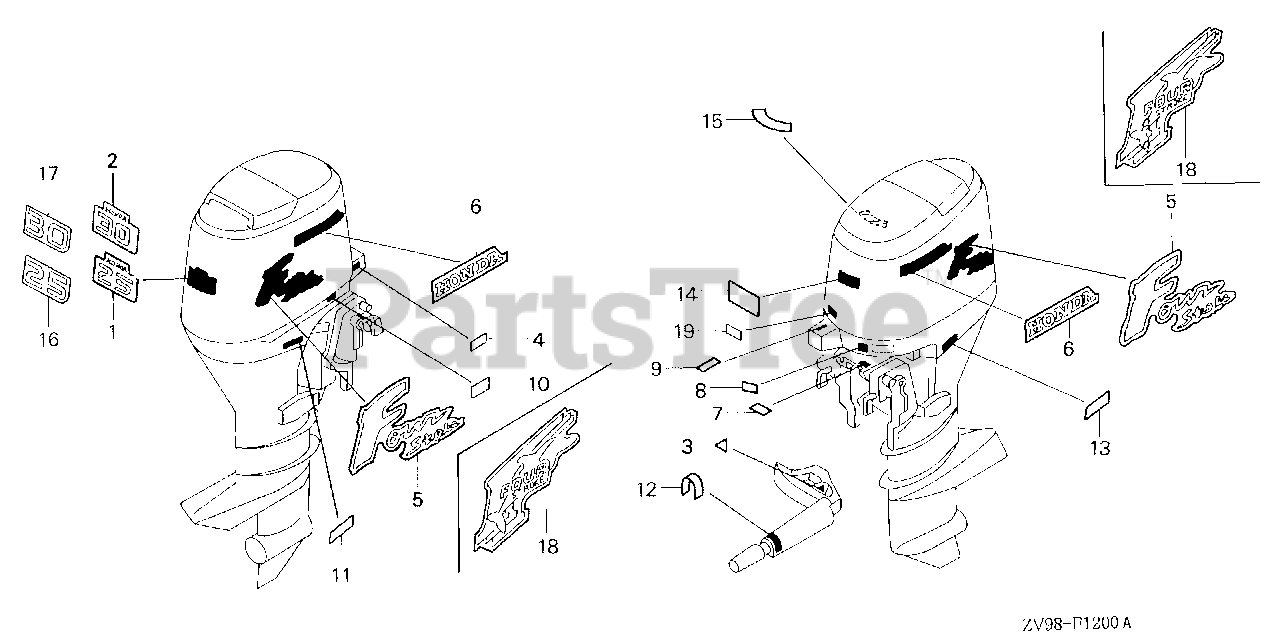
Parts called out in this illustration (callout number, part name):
6	MARK, SIDE STRIPE
7	LABEL, SPECIFICATION
11	LABEL, OIL CAUTION (ENGLISH)
13	LABEL, STORING CAUTION (ENGLISH)
14	LABEL, CAUTION OPERATOR (ENGLISH)
15	MARK, EMERGENCY START (ENGLISH)
16	MARK, RR. (25)
18	MARK, SIDE
19	MARK (E-SPEC)
